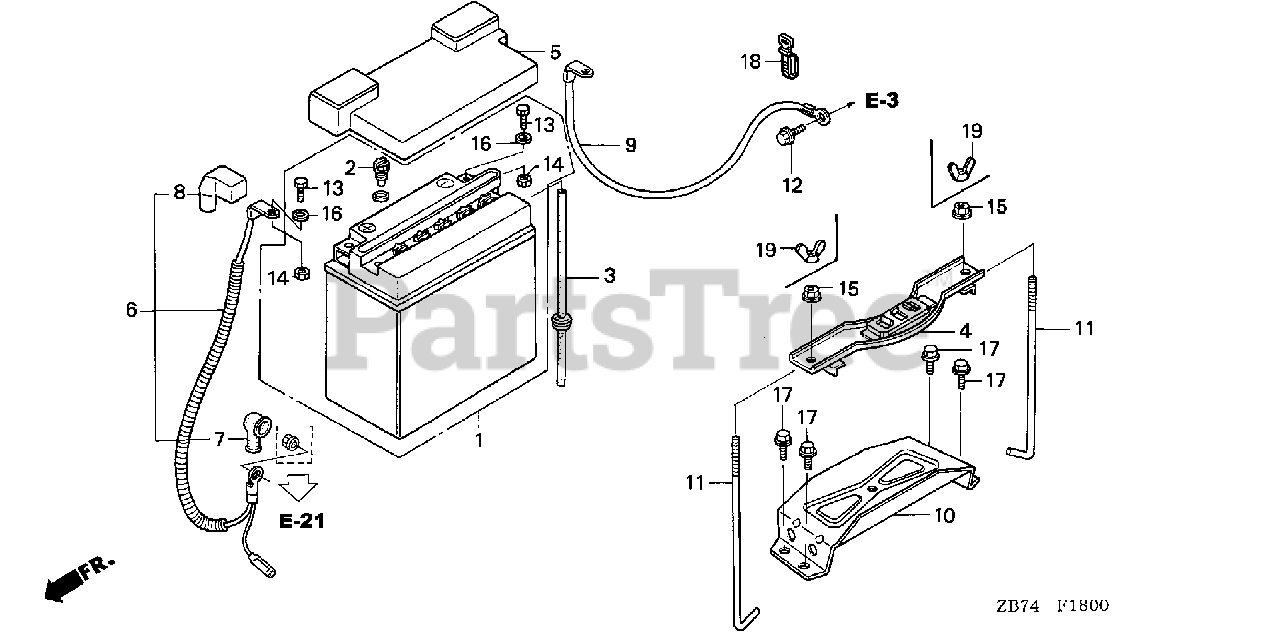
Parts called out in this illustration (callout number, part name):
1	BATTERY (YB18L-A) (YUASA)
2	PLUG, FILLING
3	TUBE, BATTERY BREATHER
4	PLATE, BATTERY SETTING
5	COVER, BATTERY
6	CABLE ASSY., STARTING
7	COVER B, MAGNETIC SWITCH
8	COVER, BATTERY TERMINAL
9	CABLE ASSY., GROUND
10	BASE, BATTERY
11	BOLT, BATTERY SETTING
12	BOLT, FLANGE (6X12) (CT200)
13	BOLT, BATTERY TERMINAL
14	NUT, BATTERY TERMINAL
16	WASHER, BATTERY TERMINAL
17	BOLT, FLANGE (6X12)
18	BAND B1, WIRE
19	NUT, TOOL BOX SETTING
